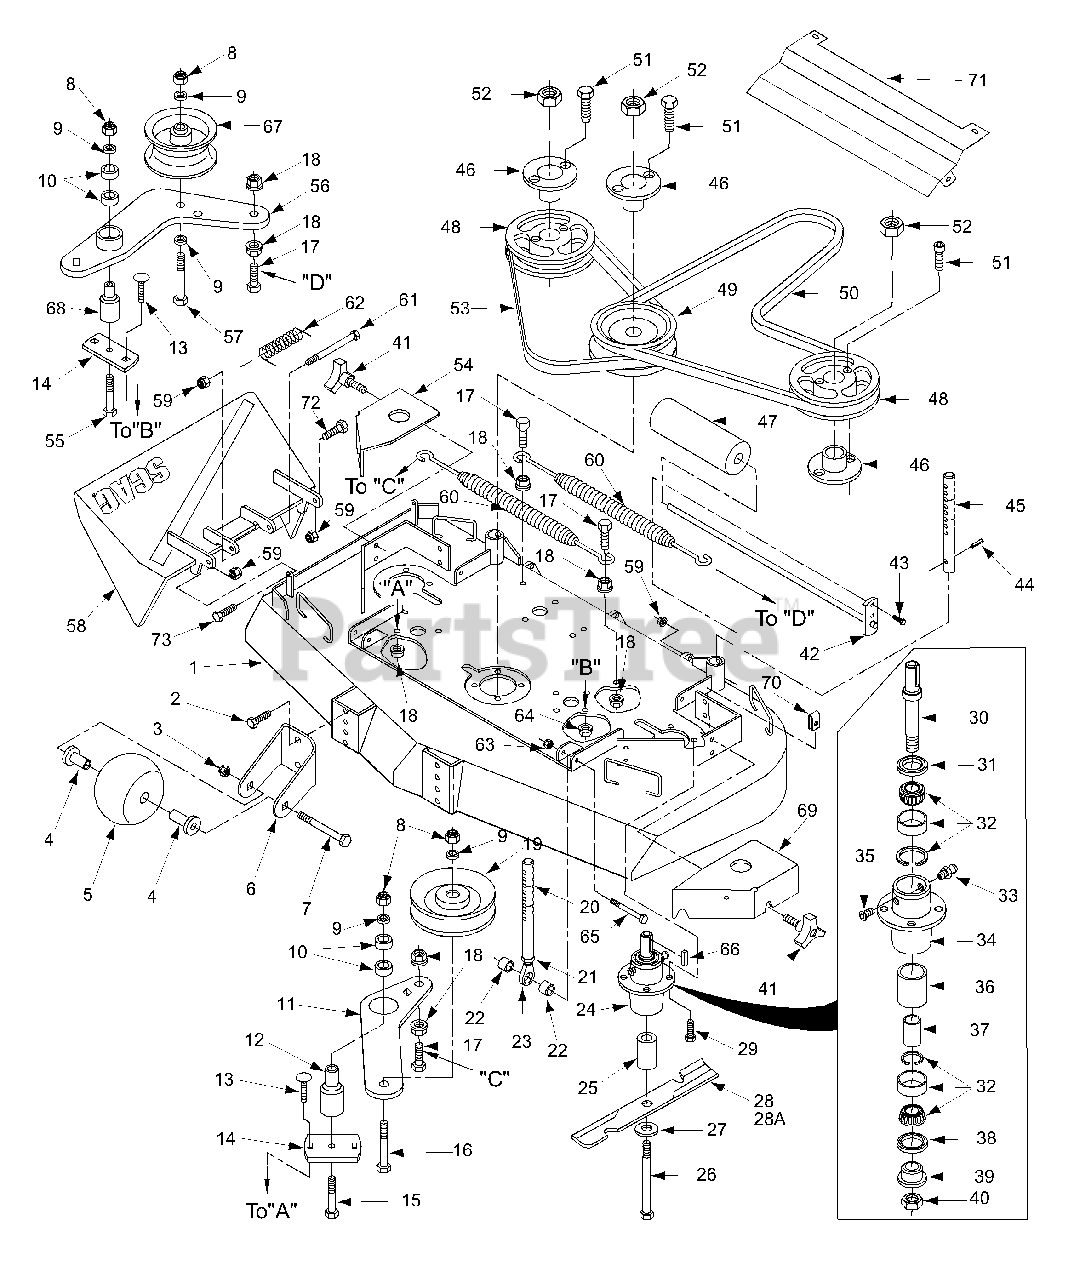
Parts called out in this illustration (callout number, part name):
1	Cutter Deck W/ Decals
2	Capscrew, 3/8-16 x 1.0" Serr. Flng.
3	Lock Nut, 3/8-16 Center Lock
4	Bushing, 376 ID Oilite
5	Wheel, Anti-Scalp
6	Bracket, Anti-Scalp Wheel
7	Bolt, Carriage 3/8-16 x 4.0"
8	Hex Nut, 3/8-16 Elastic Stop
9	Flatwasher, 3/8 (.938 x .391 x .105)
10	Ball Bearings
11	Idler Arm RH
12	Pivot, Idle - Short
13	Bolt, Carriage 5/16-18 x 1.0"
14	Base, Idler Pivot
15	Capscrew, Hex Head 3/8-16 x 2.50"
16	Capscrew, Hex Head 3/8-16 x 2.0"
17	Capscrew, Hex Head 3/8-16 x 1.50"
18	Nut, 3/8-16 Serrated Flange
19	Pulley, Idler
20	Pin Assembly
21	Nut, 3/8-24 Jam
22	Spacer, Deck Adjustment Pin
23	Rod End, Male 3/8-24
24	Spindle Assembly
25	Spacer, Spindle
26	Bolt,Hex Head 5/8-11 x 9.50"
27	Flatwasher, 5/8 W
28	Cutter Blade 16-1/2"
28A	Cutter Blade 16-1/2" Hi Lift
29	Bolt, Hex Head 5/16-18 x 1.5"
30	Spindle Shaft
31	Seal, Cutter Spindle - Top
32	Tapered Bearings (Two)
33	Grease Fitting
34	Spindle Housing
35	Relief Fitting, Cutter Spindle
36	Spacer Outside
37	Spacer, Inside
38	Seal, Cutter Spindle - Bottom
39	Spindle Bushing
40	Nut, Spindle
41	Wing Nut, 3/8-16
42	Roller Shaft
43	Bolt, Hex Head 5/16-18 x 1.0"
44	Pin, Slotted Spring 3/16 x 1.50"
45	Pin, Deck Adjustment Rear
46	Tapered Hub
47	Guide, Roller
48	Pulley
49	Pulley, 5.75 Double Groove
50	Belt, Deck Drive
51	Capscrew, Sckt. Hd. 1/4-20 x 1.375"
52	Hex Nut, 5/8-11
53	Belt, Cutter Deck RH
54	Belt Cover, RH
55	Capscrew, HH 3/8-16 x 3.25"
56	Idler Arm Weldment
57	Capscrew, Hex Head 3/8-16 x 3.75"
58	Discharge Chute
59	Nut, 5/16-18 Serrated Flange
60	Spring, Deck Idler
61	Bolt, Hex Head 5/16-18 x 4.25"
62	Spring, Chute Return
63	Nut, 3/8-16 Elastic Stop
64	Nut, 5/16-18 Serrated Flange
65	Bolt, Hex Head 3/8-16 x 2.50"
66	Key, 1/4 x 1/4 x 2.0"
67	Pulley, Idler
68	Pivot, Idler - Long
69	Belt Cover LH
70	U-Nut, 3/8-16
71	Heatshield (small frame - 16" wide)
72	Bolt, Hex Head 5/16-18-1.5"
73	Bolt, Hex Head 5/16-18 x 1.75"
